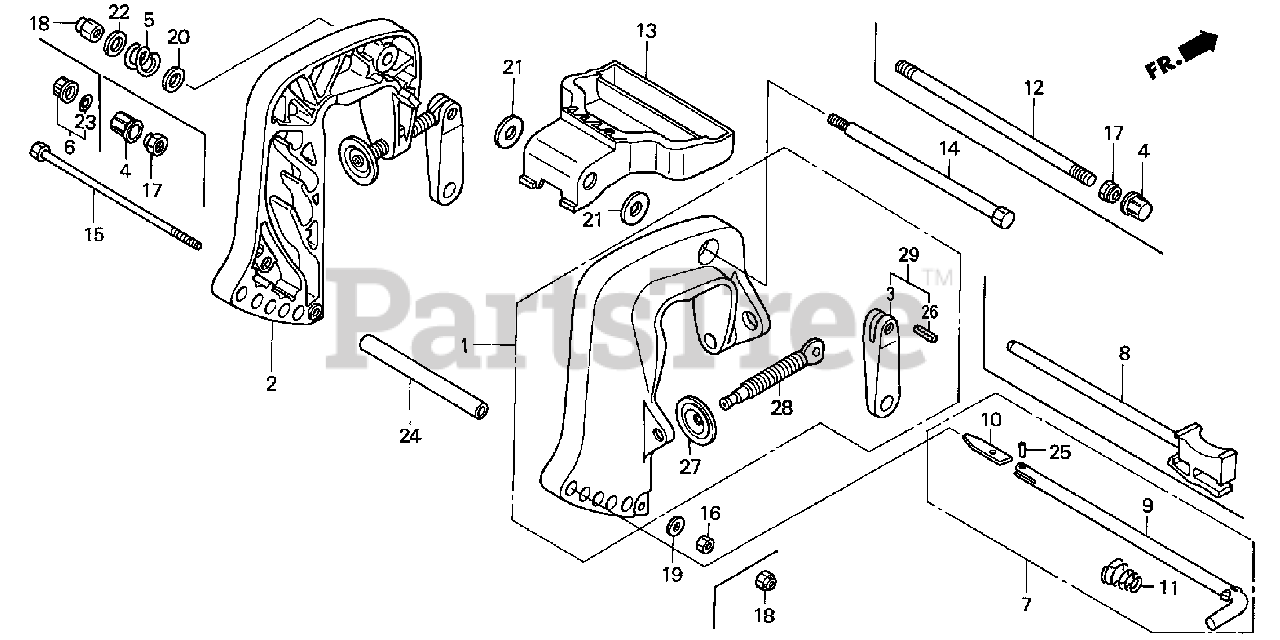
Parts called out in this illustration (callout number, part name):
1	BRACKET, R. STERN *NH282MU* (OYSTER SILVER METALLIC-U)
2	BRACKET, L. STERN *NH282MU* (OYSTER SILVER METALLIC-U)
3	GRIP, CLAMP
7	ROD, ADJUSTING
9	ROD, ADJUSTING
10	STOPPER, ROD
11	SPRING, ROD ADJUSTING
12	SHAFT, TILTING
13	HANDLE, CARRYING REMOTE
15	BOLT, HEX. (8X163)
17	NUT, SELF-LOCK (7/8-14UNF)
18	NUT, SELF-LOCK (8MM)
19	WASHER, PLAIN (6MM)
21	WASHER, WAVE (22MM)
23	O-RING (15.54X2.26)
24	COLLAR, DISTANCE
25	PIN, SPRING (2.5X8)
26	RIVET (4X22.6)
27	PLATE, PUSH
28	SCREW, CLAMP
29	GRIP KIT, CLAMP
